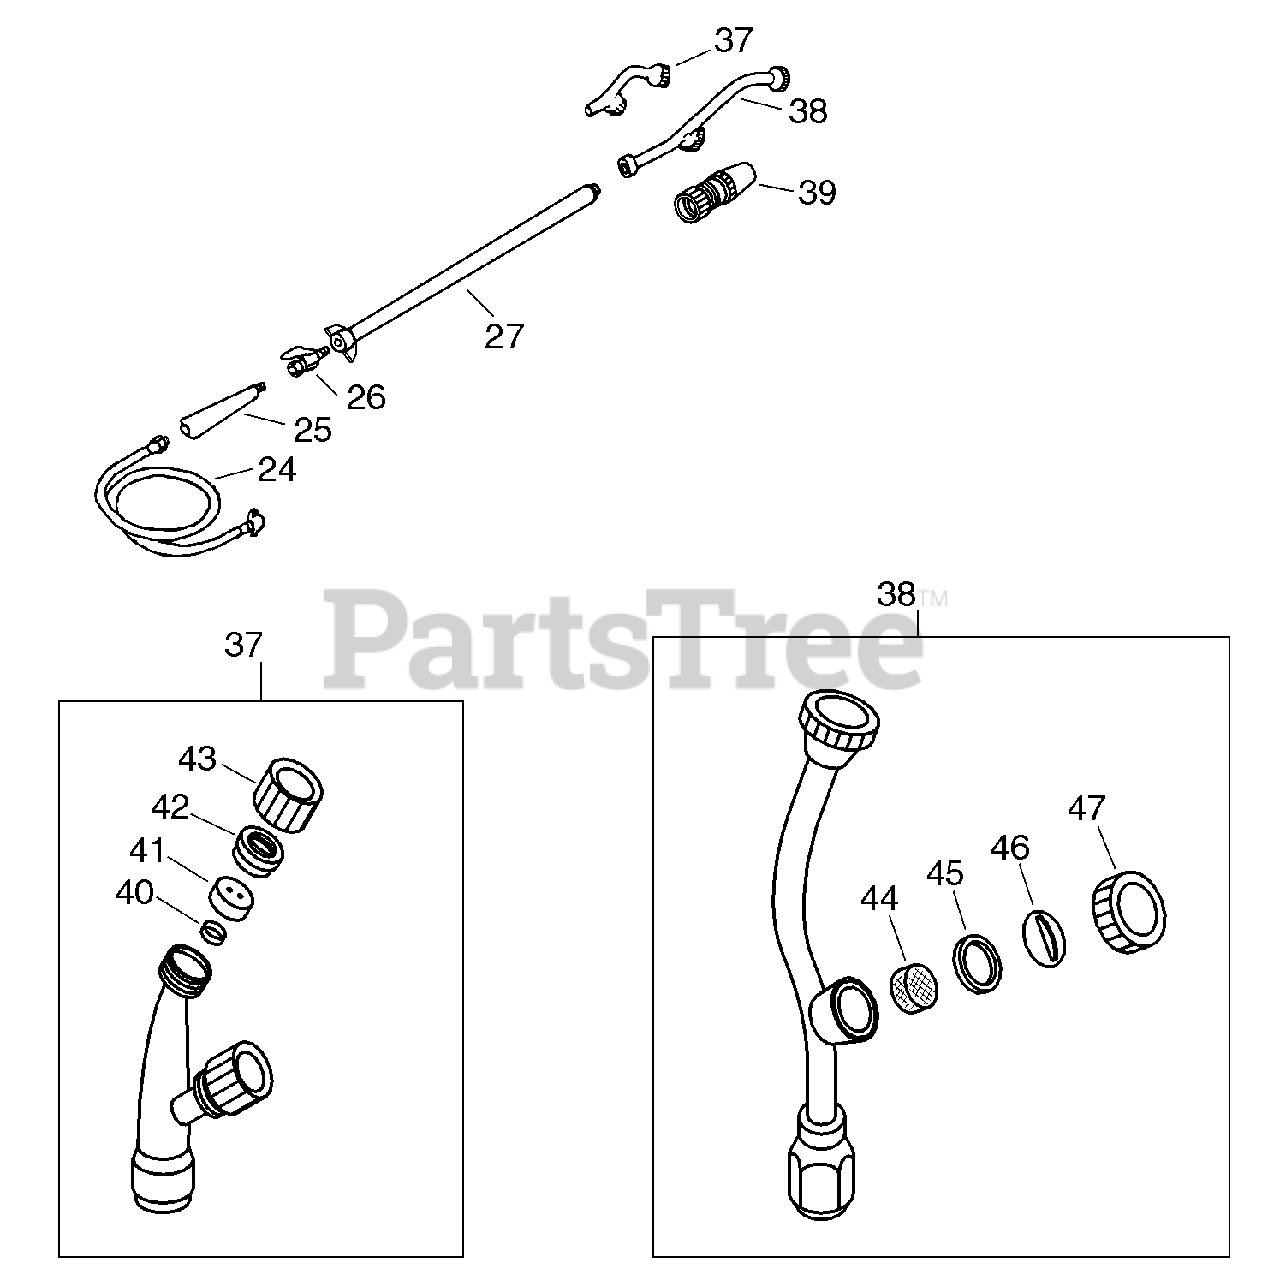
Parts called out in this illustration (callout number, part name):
24	SPRAY HOSE ASSY
37	NOZZLE - PLASTIC -- D-8
38	NOZZLE - METAL
39	NOZZLE - NO.33
43	CAP, NOZZLE
46	TIP - NOZZLE -- K-5
47	CAP, NOZZLE
